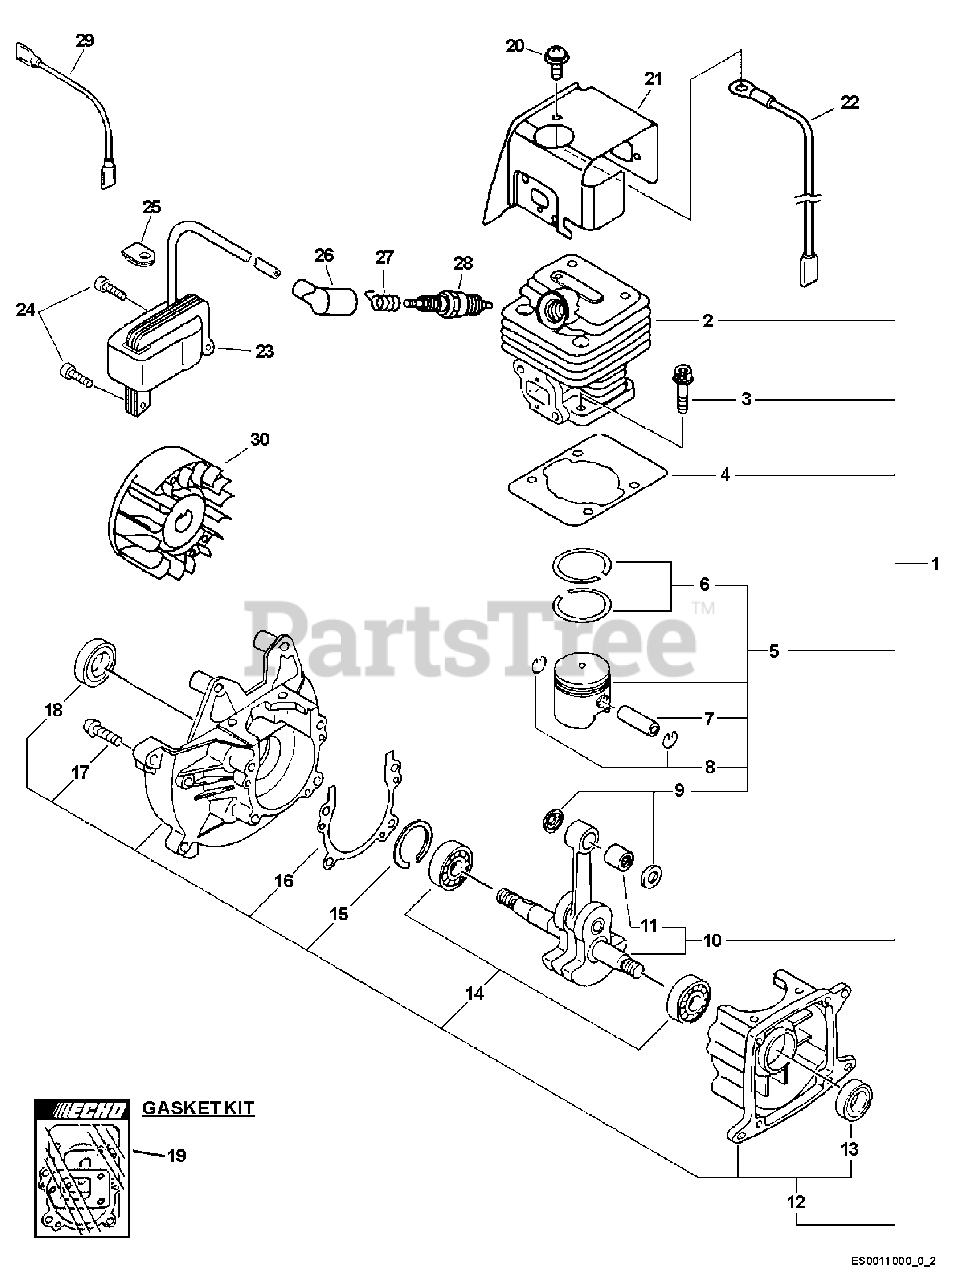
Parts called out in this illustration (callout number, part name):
1	SHORT BLOCK -- SB1045
2	CYLINDER
3	SCREW - 5X22
4	GASKET, CYLINDER
5	PISTON KIT
6	RING, PISTON
7	PIN, PISTON
8	RING, RETAINING
9	SPACER, PISTON
10	CRANKSHAFT ASSY
11	BEARING, NEEDLE - 8
12	CRANKCASE KIT
13	SEAL, OIL
14	BEARING, BALL - 6001C3
15	RING, RETAINING - 28
16	GASKET, CRANKCASE
17	SCREW - 5X25
18	SEAL, OIL - 12
19	GASKET KIT
20	SCREW - 5X10
21	SHIELD, CYLINDER
22	LEAD - GROUND
23	COIL, IGNITION
24	SCREW - 5X16
26	CAP, SPARK PLUG
27	TERMINAL, SPARK PLUG CAP
28	SPARK PLUG -- BPM-7Y
29	LEAD - IGNITION
30	FLYWHEEL
